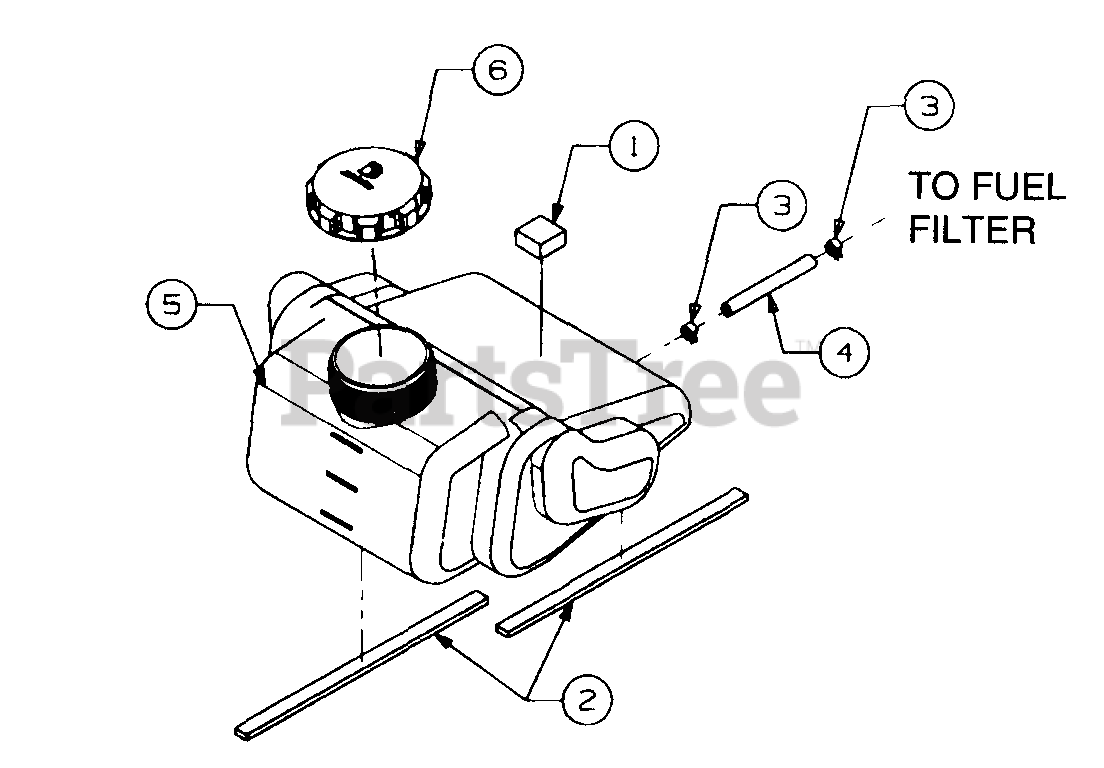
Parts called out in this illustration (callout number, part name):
1	Foam, 1.25 Sq x .62 Thk
2	Tape, Foam, .625 Wide x .25 Thk
3	Clamp, Hose
4	Line, Fuel, 72 in Lg
5	Tank, Fuel
6	Cap, Fuel
